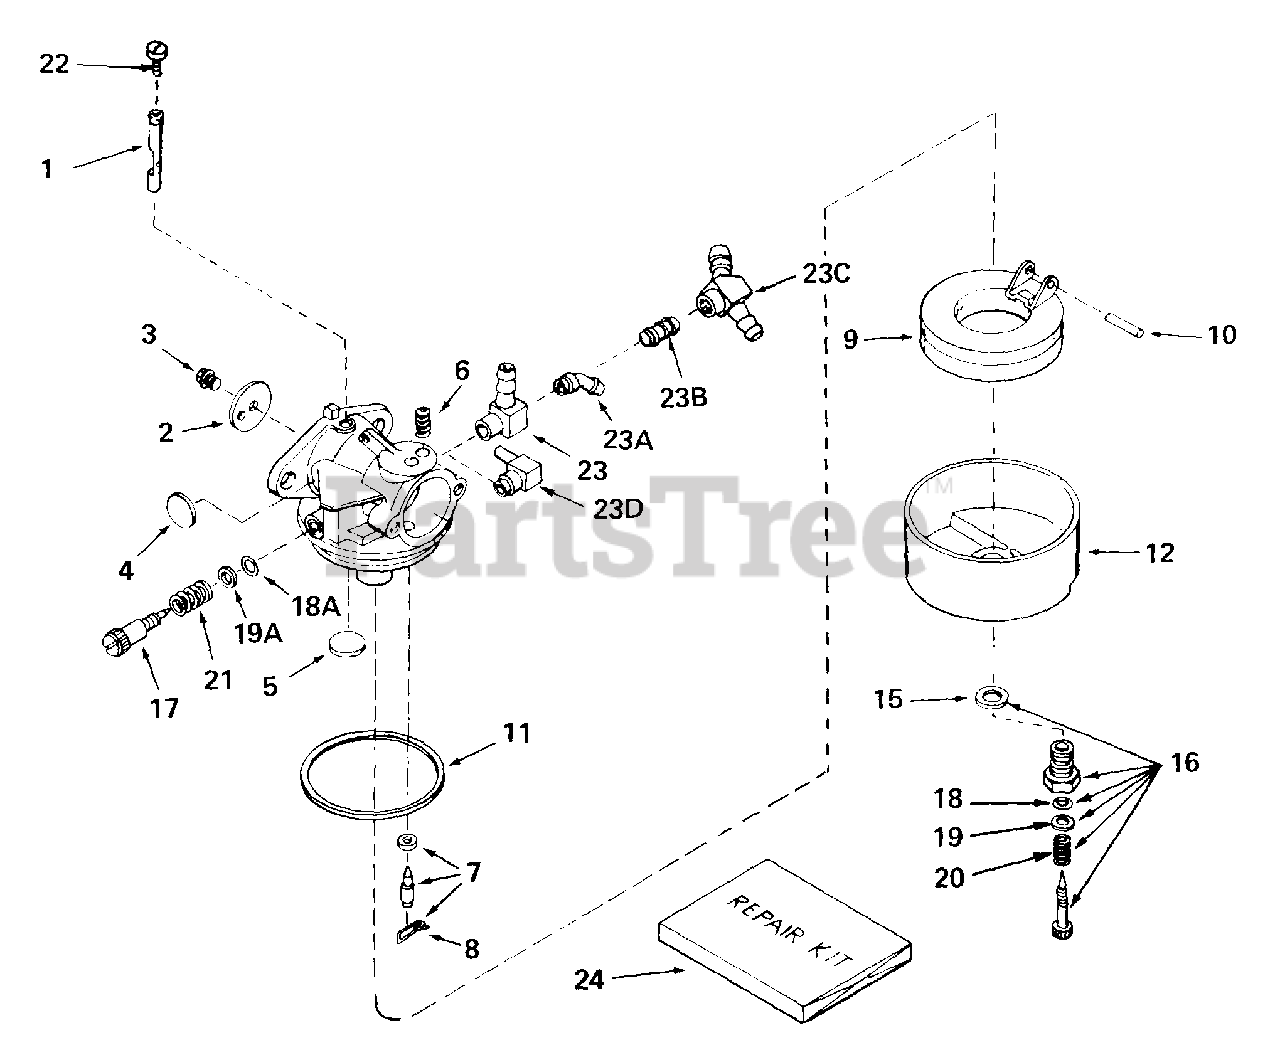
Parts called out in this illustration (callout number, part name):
1	"Shaft, Throttle
2	Shutter, Throttle
3	Screw, 4-40 x 3/16
4	Plug, Welch
5	Plug, Welch
6	Spring, Choke positioning
7	Inlet Needle, Seat & Clip
8	Clip, Inlet needle
9	Float, Carburetor
10	Shaft, Float.
11	Gasket, Bowl-to-body
12	Bowl, Float
15	Gasket, Bowl-to-Body
16	Adjustment Screw Assy., Main
17	Screw, Idle adjustment
18	"O" Ring, Adjustment screw
18A	"O" Ring, Adjustment screw
20	Spring, Adjustment screw
21	Spring, Adjustment screw
23	Fitting, Fuel inlet
23A	Fitting, Fuel inlet
23C	Fitting, Fuel inlet
24	Repair Kit
